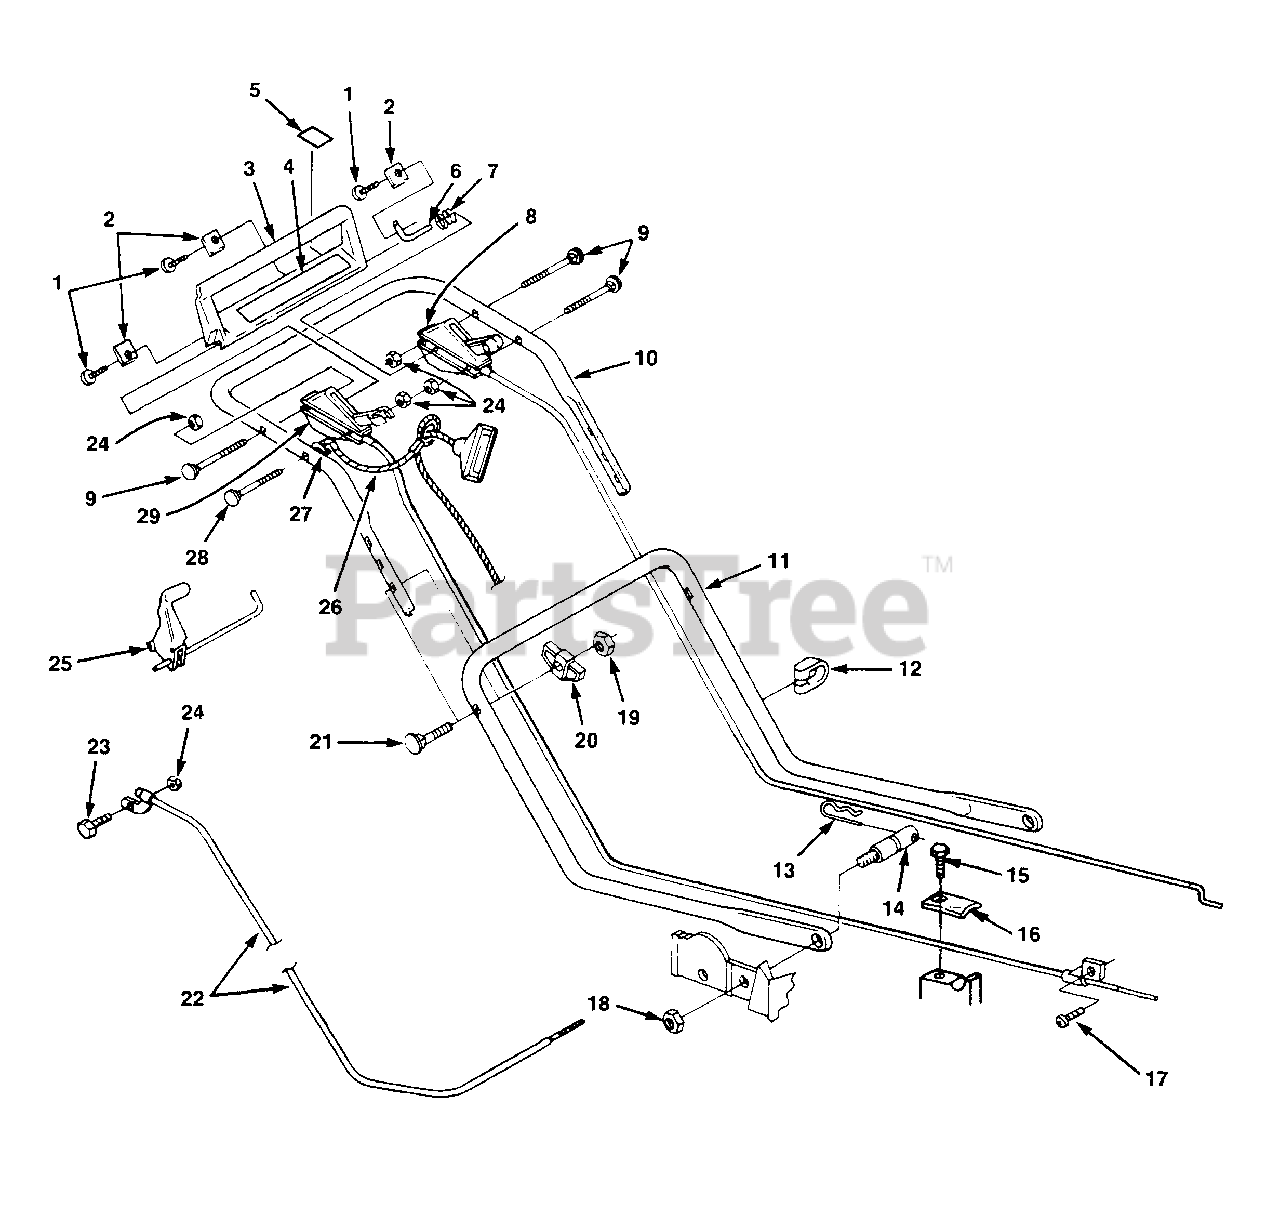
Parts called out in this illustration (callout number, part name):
1	SCREW- 1/4-10 x 5/8"
2	CLAMP- Pivot shaft
3	BAIL- Brake control
4	DECAL- Brake bail
5	DECAL- Blade rotation
6	SHAFT- Pivot (short)
7	SPRING- Compression
8	CONTROL- Throttle
9	BOLT- Sq. neck 1/4-20 x 2"
10	HANDLE- Upper
11	HANDLE- Lower
12	CABLE- Tie
13	PIN- Cotter hair
14	STUD- Handle mtg.
15	SCREW- Hex hd. 1/4-20 x 5/8"
17	SCREW- Hex hd. 10-32 x 3/8"
18	NUT- Hex flange 5/16-18
19	NUT- Hex 5/16-18
20	KNOB- Handle
21	BOLT- Sq. neck
22	CABLE- Traction
23	SCREW- Hex hd. 1/4-20 x 1 1/2"
24	NUT- Hex locking 1/4-20
25	LEVER- Traction
26	ROPE- Restraint
27	WASHER- Curved
28	BOLT- Sq. neck 1/4-20 x 2 1/4"
29	CONTROL- Manual start
